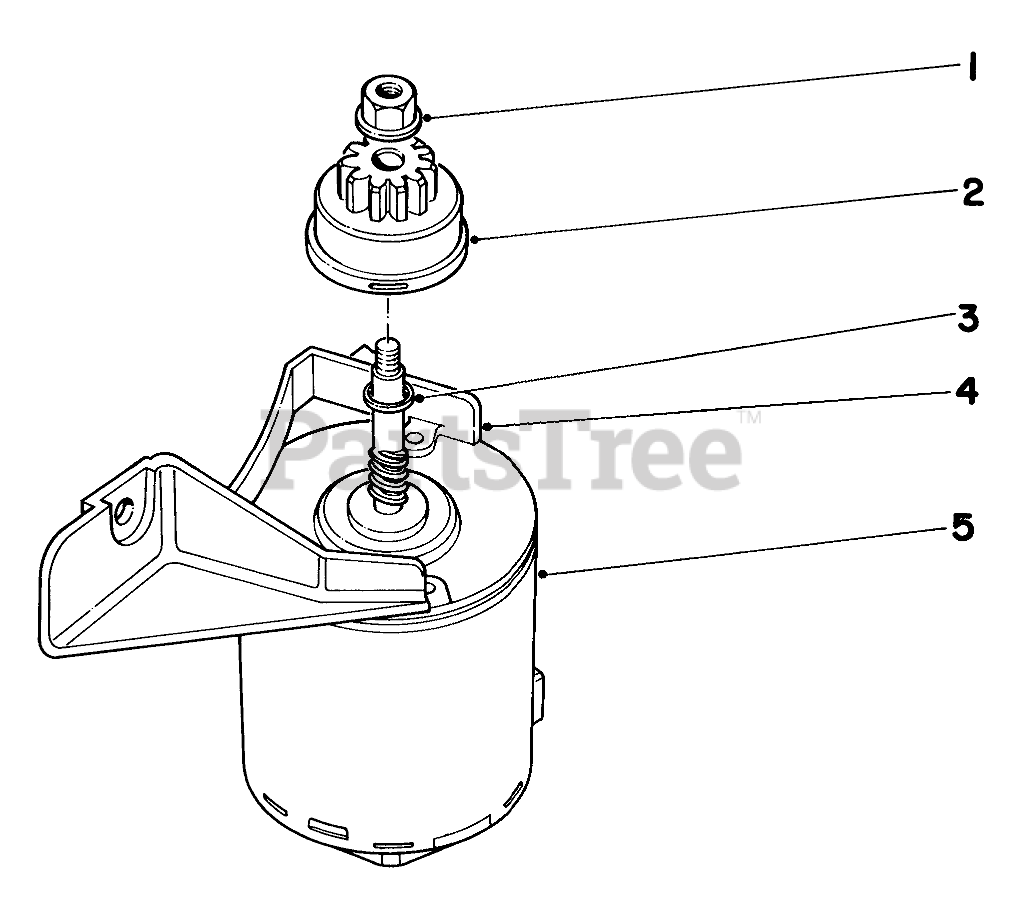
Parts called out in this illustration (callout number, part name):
1	NUT-HHF
2	Pinion Assemble
3	Spacer
4	Mounting Bracket
5	Starter Motor (Incl. Ref. #1-3)
